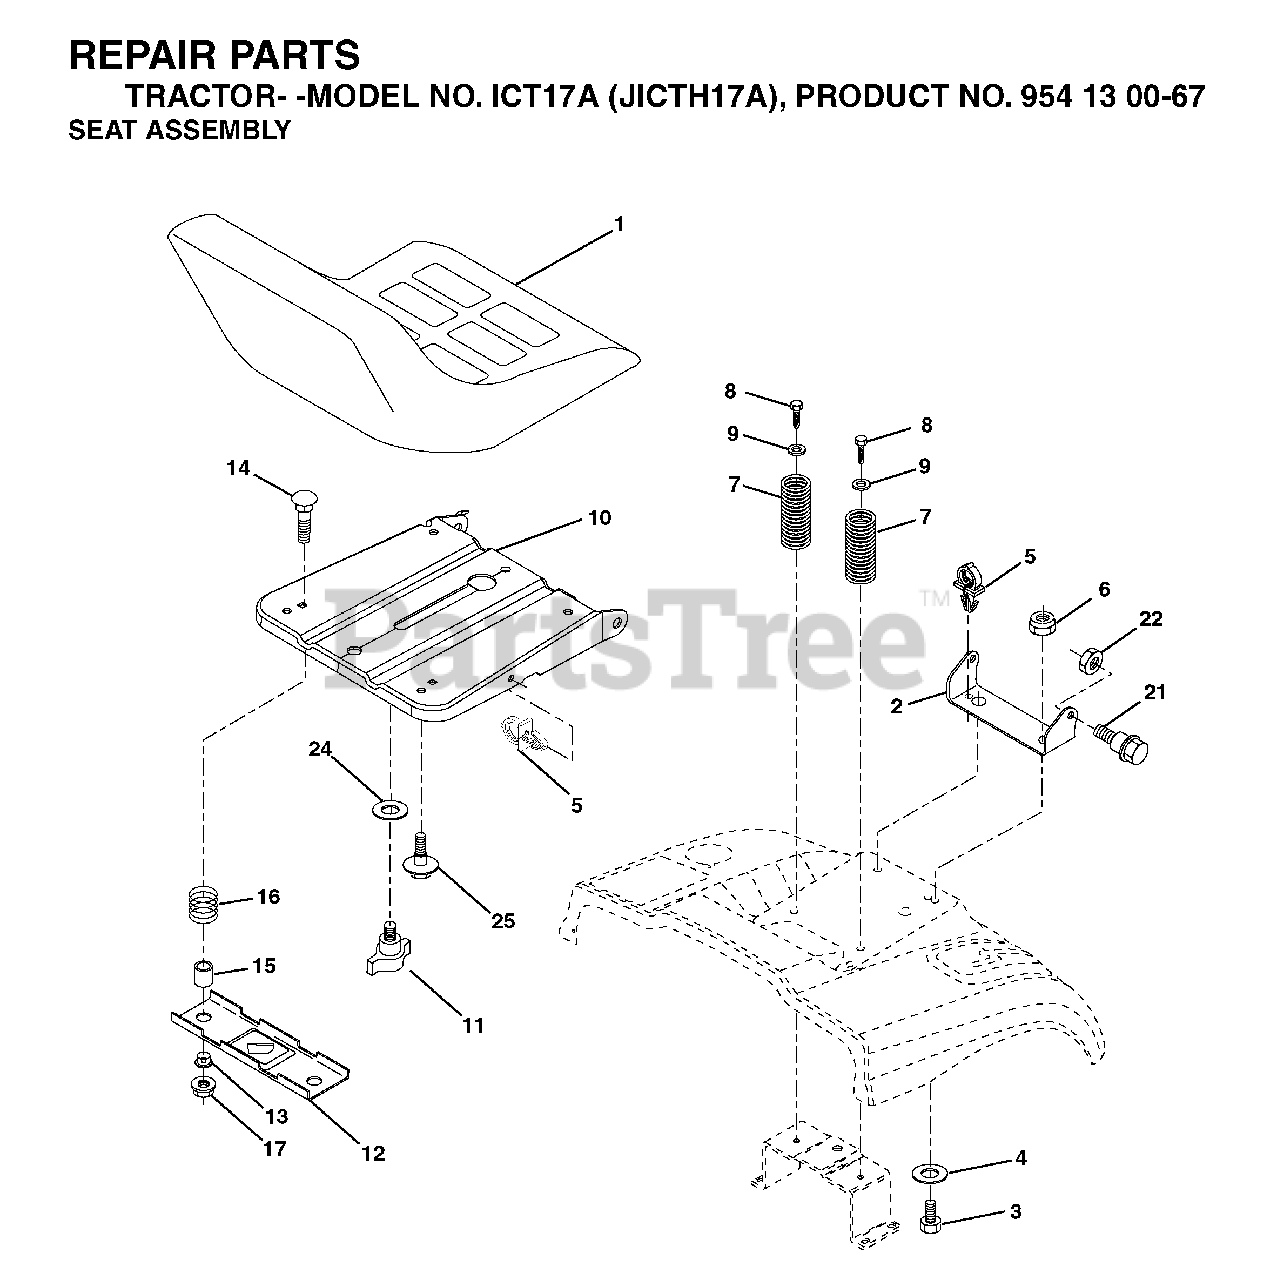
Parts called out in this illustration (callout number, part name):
2	SEAT PIVOT BRKT
4	WASHER PM
5	PUSH CLIP
6	NUT
7	SPRING COMPRESSION
8	SCREW 3/8-16X1
9	WASHER
10	PAN SEAT
11	KNOB.SEAT.ADJ.WINGNUT
12	BRKT SWITCH
14	BOLT.ROUND.HEAD.SQUARE.NECK
15	SPACER SPLIT
16	SPRING COMPRESSED
17	NUT T
21	BOLT.SHOULDER.5/16-18
22	NUT.71038.31-18.HEX.NYLOCK
25	BOLT,SHOULD
